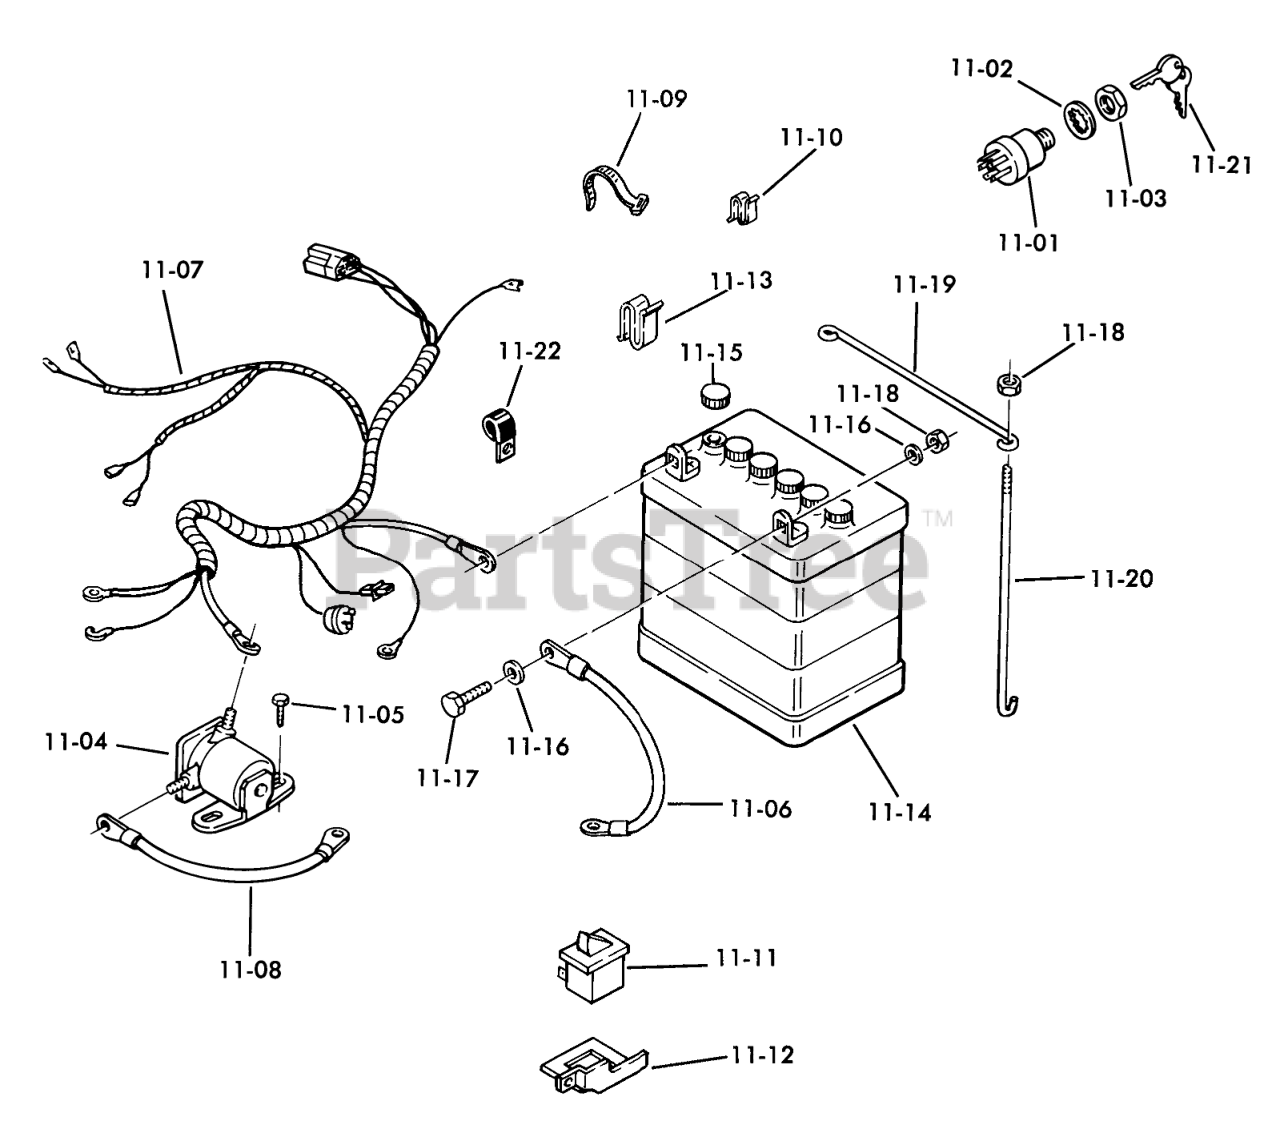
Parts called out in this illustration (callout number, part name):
11-01	ASSY-SWITCH IGNITION
11-02	LOCKWASHER
11-04	Solenoid
11-05	S.T. Screw 1/4-20 x 3/4
11-06	Ground Wire
11-07	Wire Harness
11-08	Wire
11-09	PLASTIC TIE
11-10	SPEED CLIP
11-11	SWITCH INTERLOCK
11-12	Bracket-Switch
11-13	CLIP
11-14	Battery
11-17	Bolt
11-18	Nut
11-19	ROD-HOLD DOWN
11-20	Hook
11-21	Key-EL
11-22	CLAMP
